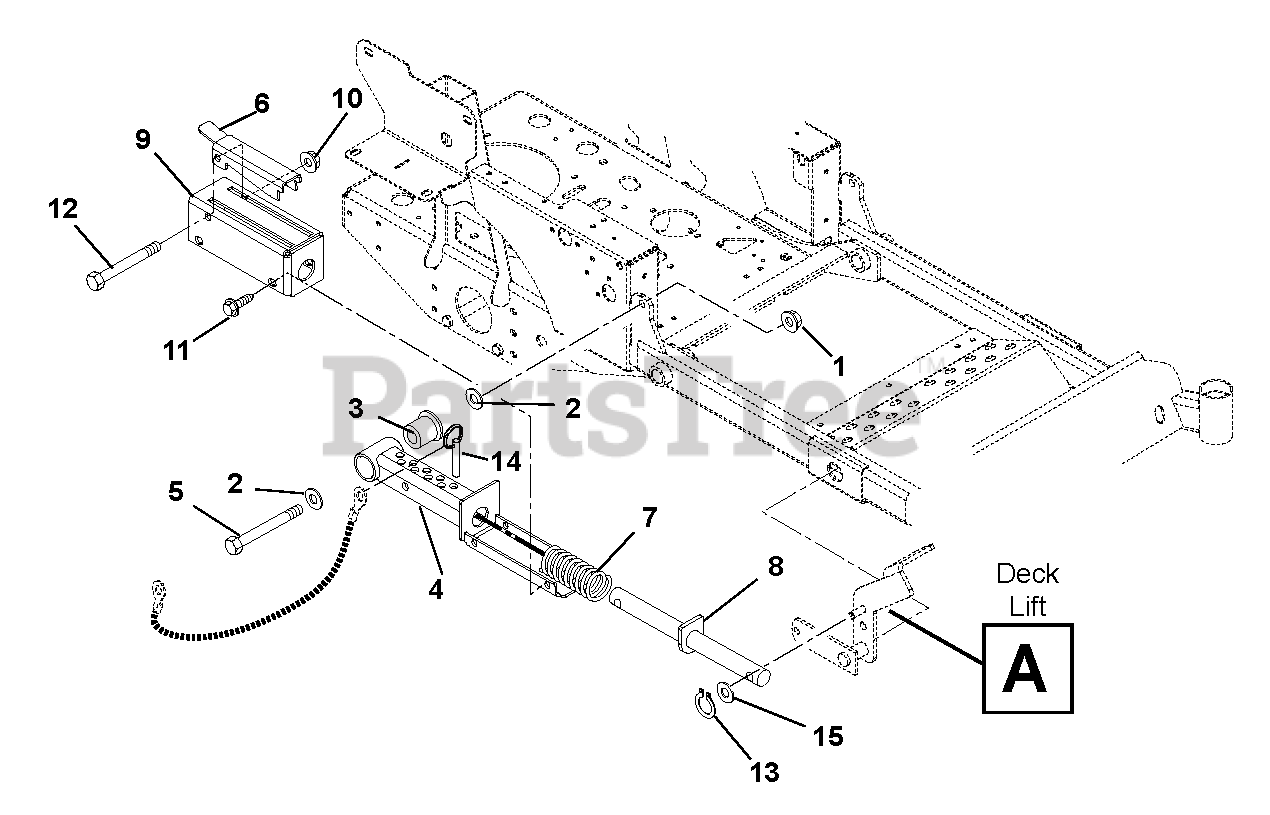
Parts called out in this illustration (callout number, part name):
1	Nut, Locking Top Flange .50-13
2	Washer, Flat Steel .531 x 1.25 x .10
3	Bearing, Pedestal
4	Weldment, Mechanical Lift
5	Bolt, Hex .50-13 x 3.75 Grade 5
6	Lock-Up, Mechanical Lift
7	Spring, Compression 1.13 x 1.48 x 5.10
8	Weldment, Mechanical Lift Shaft
9	Weldment, Mechanical Lift Cover
10	Nut, Nyloc Flange 3/8-16
11	Screw, Tapping .38-16 x .50 Hex Washer Head
12	Bolt, Hex .38-16 x 3.25 Grade 5
13	Ring, Retaining External .50 x .05
14	Pin, Spring Ball .375 O.D. x 1.50
15	Washer, Flat Steel .531 x 1.25 x .10
